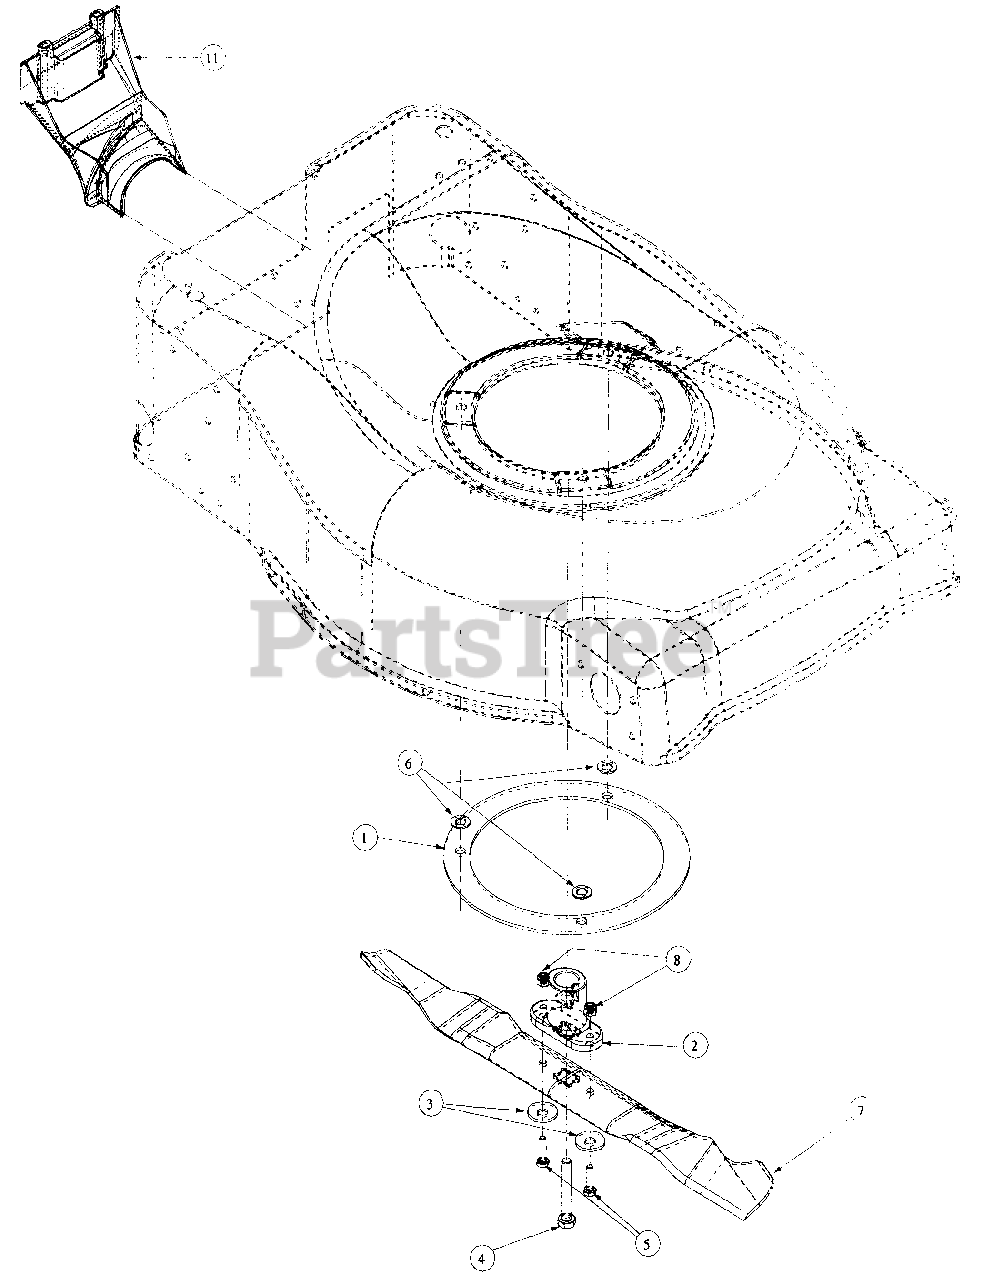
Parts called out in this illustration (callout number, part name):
1	Engine Mount Support Plate, W/O BBC
2	Blade Adapter, 6 x 2.15 W/Star
3	Bell Washer,,396 x 1.140 x .095
4	HHCS: 3/8-24, 2.50, Group 8, Spec
5	HHCS, 1/4-20, 1.00, Group 5, Spec
6	Flat Washer, 3/8 X .738 X .063
7	Blade: 21" Mulching W/Star
8	Hex Nut, 1/4-20, GRC, Lock
